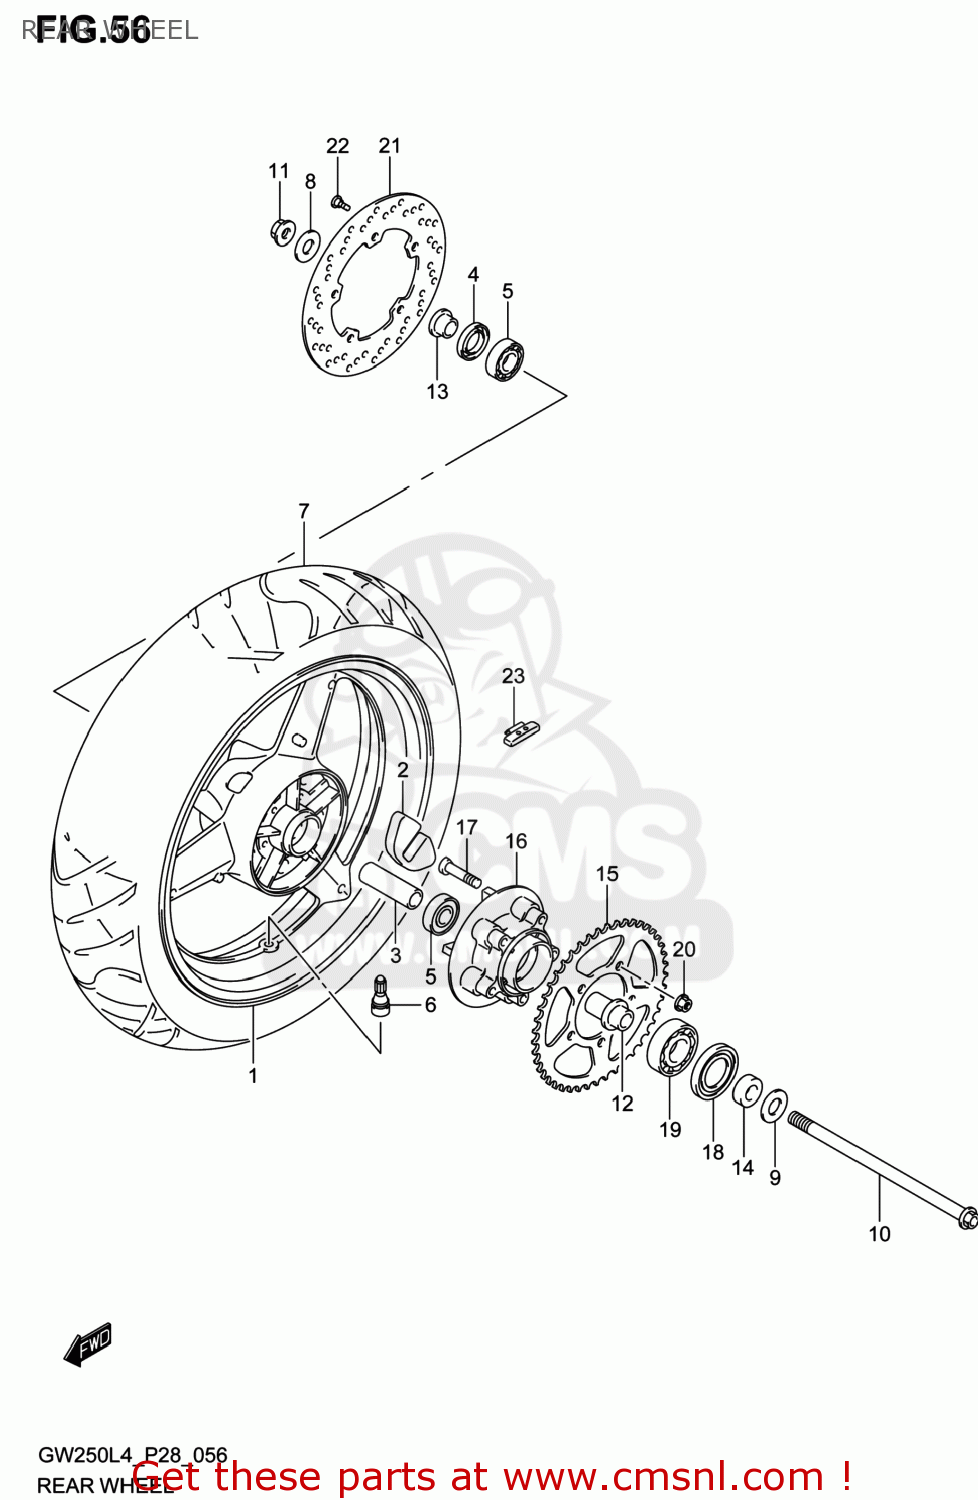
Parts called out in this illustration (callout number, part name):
1	WHEEL,RR(17M/CXMT4.00)
2	ABSORBER,RR HUB SHOCK
3	SPACER(17.5X25X78)
4	SEAL,OIL(25X47X8)
5	BEARING
6	VALVE ASSY,WHEEL RIM(TR412)
7	TIRE,RR(140/70-17M/C 66H)
8	WASHER,RR AXLE,R
9	WASHER,RR AXLE,L
10	AXLE,RR
11	NUT,RR AXLE
12	RETAINER,RR SPROCKET DRUM
13	SPACER,RR AXLE,R
14	SPACER,RR AXLE,L
15	SPROCKET,RR(46T-520)
16	DRUM,RR SPROCKET
17	BOLT(10X43.5)
18	SEAL,OIL(35X62X8)
19	BEARING(25X62X17)
20	NUT
21	DISC,RR BRAKE
22	BOLT,RR BRAKE DISC
23	BALANCER,WHEEL(10G)
